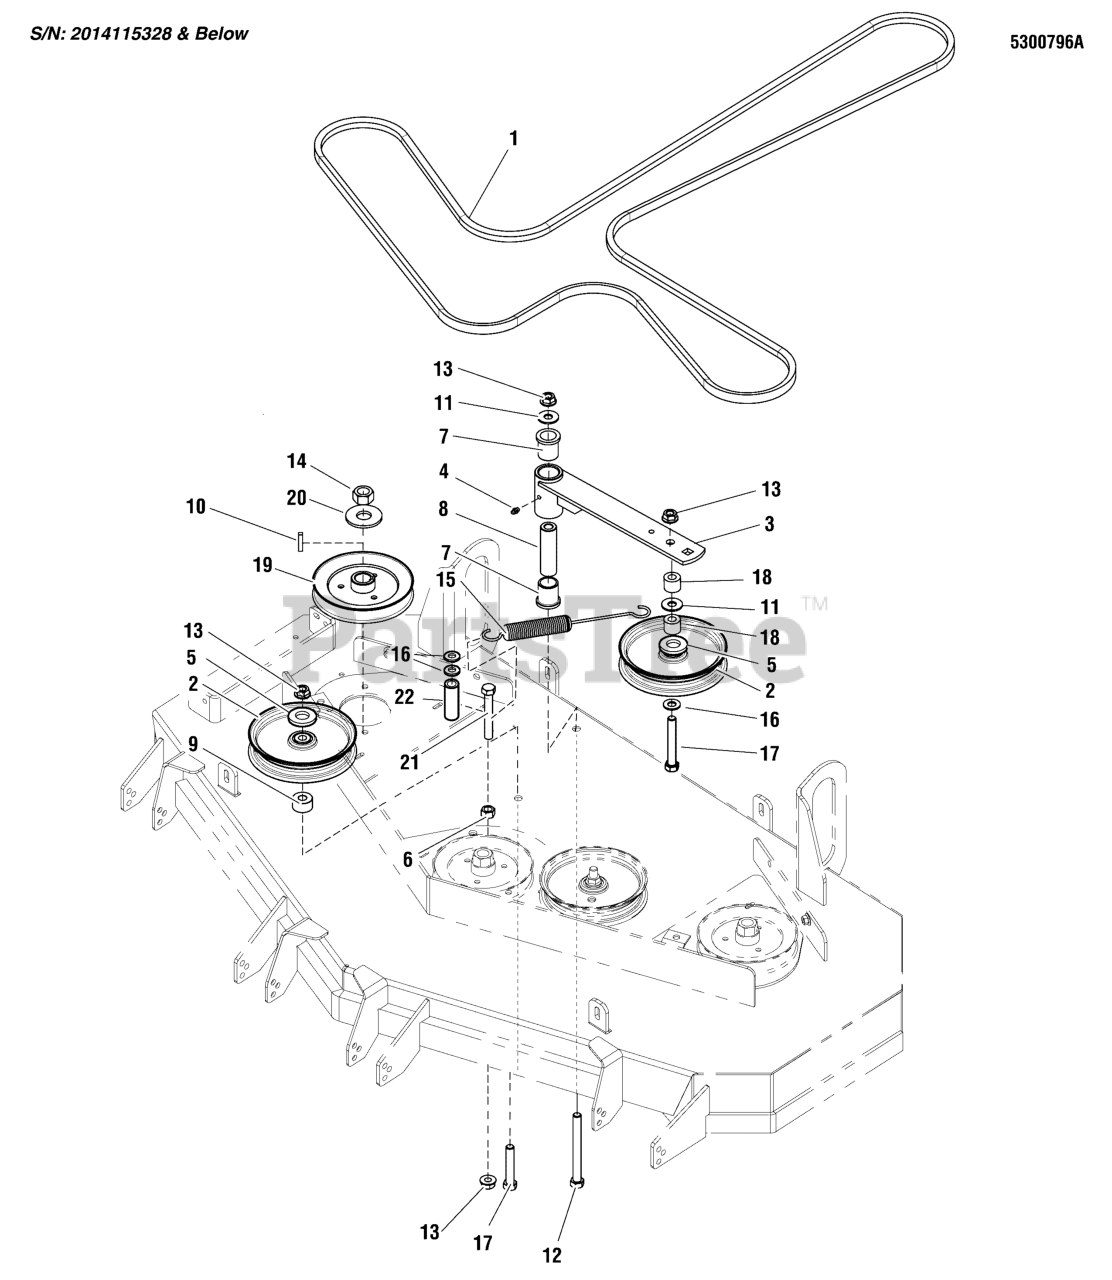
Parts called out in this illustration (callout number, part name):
1	BELT, BP-SEC, 145.4EL, ARAMID, WRPD
3	WELD, IDLER ARM (10.50)
4	GREASE FITTING, 1/4-28 STRAIGHT
5	SHIELD, PULLEY BEARING, CZ
6	NUT, 1/2-13 HEX, YZ
7	BUSHING, FLANGE
8	SPACER, .52 X .998 X 3.42
9	SPACER, .52 X 1.25 X .70, CZ
10	KEY, 1/4 SQ X 1-1/4
11	WASHER, 1/2 USS
12	BOLT, 1/2-13 X 4-1/2 GD5 YZ
13	NUT, Hex Flange, Nylock, 1/2-13
14	NUT, 3/4-16 HEX
15	SPRING-EXT, 1.04 ODX10.535LGX.148WR, BLK
16	WASHER, 1/2 SAE
17	BOLT, 1/2-13 X 3" GD5 CZ
18	SPACER, .52 X 1.00 X .44, CZ
19	PULLEY, 5.540OB X .985ID, SINGLE B-SEC
20	WASHER, 3/4 BELLEVILLE
21	BOLT, 1/2-13 X 4" GD5 CZ
22	HOSE, 1/2" PUSH-ON 2.25"
